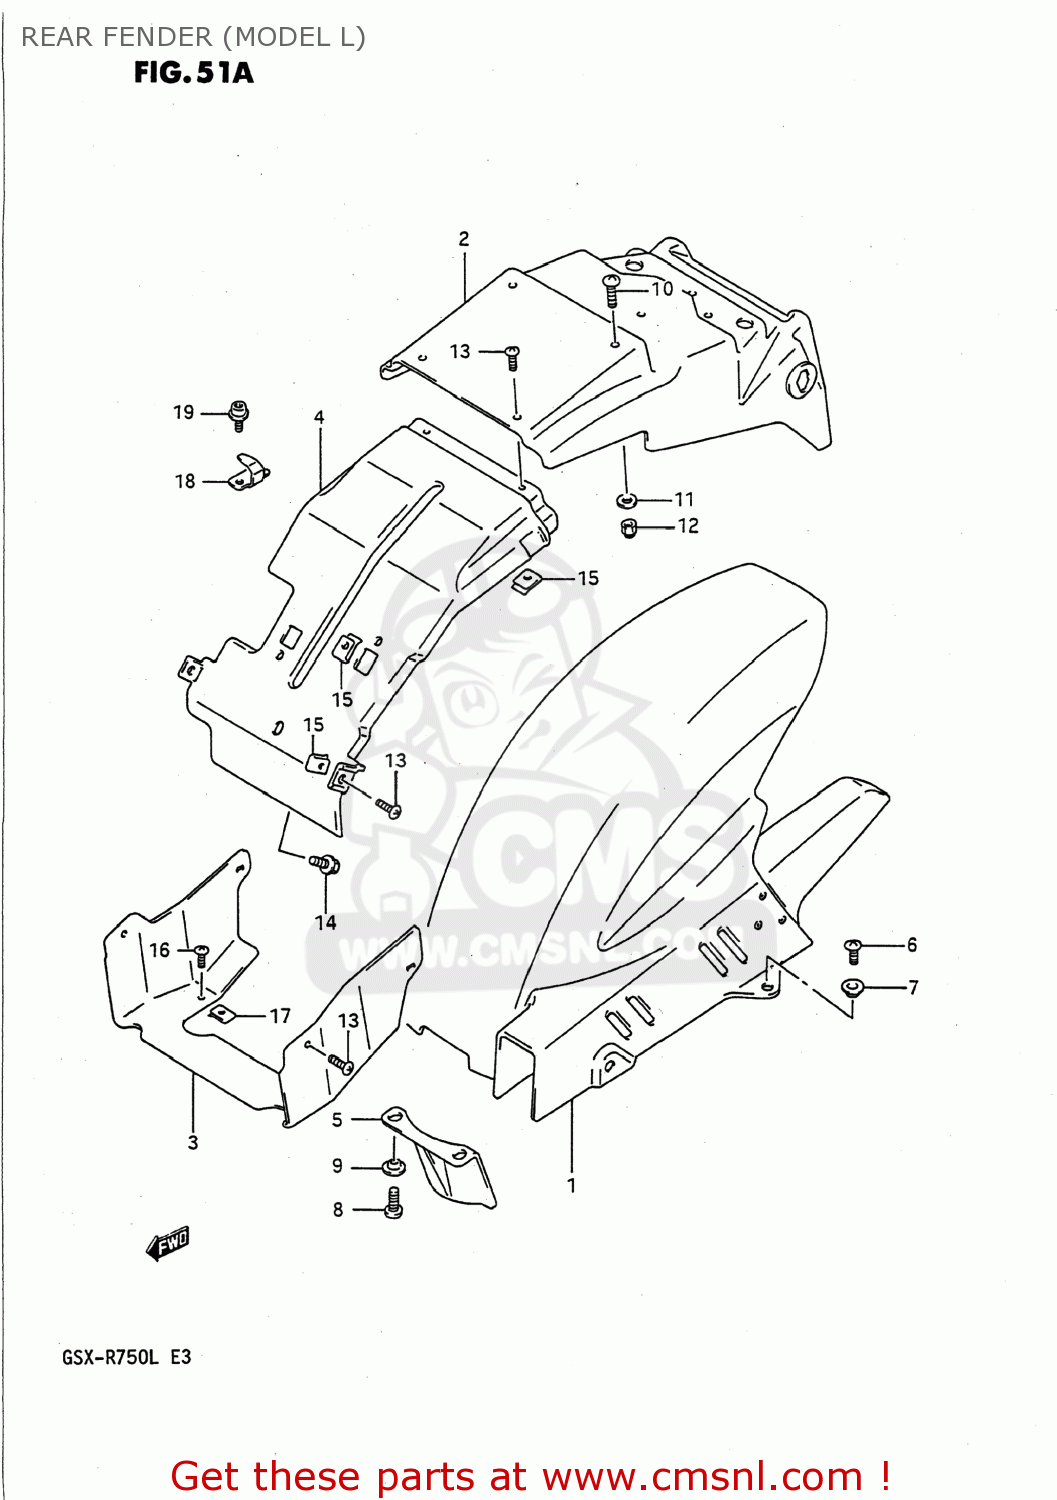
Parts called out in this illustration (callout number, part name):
1	FENDER,RR LWR
2	FENDER,REAR
3	FENDER,REAR
4	FENDER,RR UPR FR NO.2
5	GUARD,RR UNIT MUD
6	SCREW
7	WASHER
8	SCREW
9	WASHER,LOCK
10	SCREW
11	WASHER
12	NUT
13	SCREW, FRONT & REAR
14	BOLT
15	NUT,HEADLAMP HOUSING,UPPER
16	SCREW, FRONT & REAR
17	NUT,HEADLAMP HOUSING,UPPER
18	HOLDER,HELMET
19	BOLT
